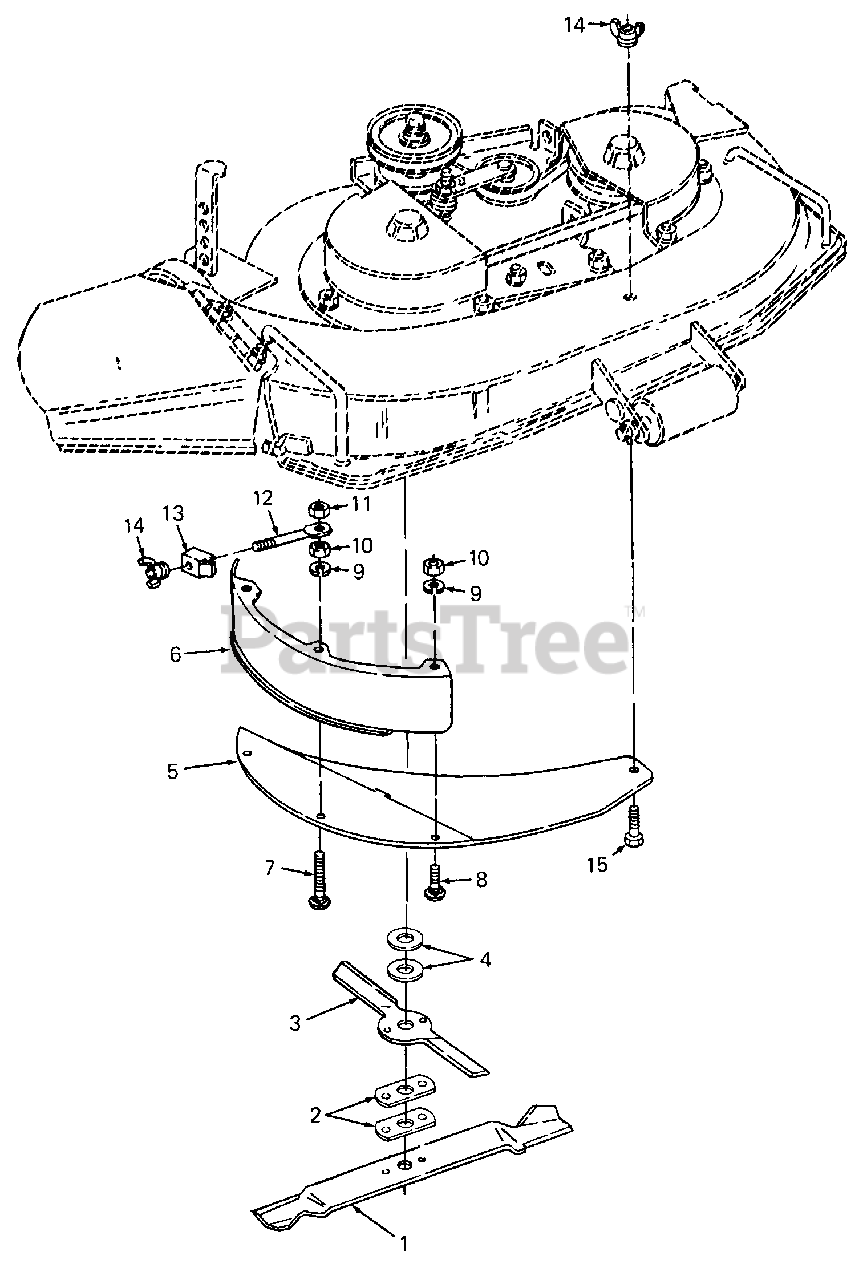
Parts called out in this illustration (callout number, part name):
1	Blade, Low Lift, 19.38 Lg
5	Baffle, Top Mulching
6	Baffle, Side Mulching
7	Bolt, Carriage, 1/4-20 X 1.0 Lg
8	Bolt, Carriage, 1/4-20 X .62 Lg
9	Washer, Lock, 1/4
10	Nut, Hex, 1/4-20 GR5
11	Nut, Hex Center Lock, 1/4-20
12	Bolt, Retaining
14	Nut, Nylon Wing, 1/4-20
15	Screw, Hex Cap, 1/4-20 X .62 Lg
